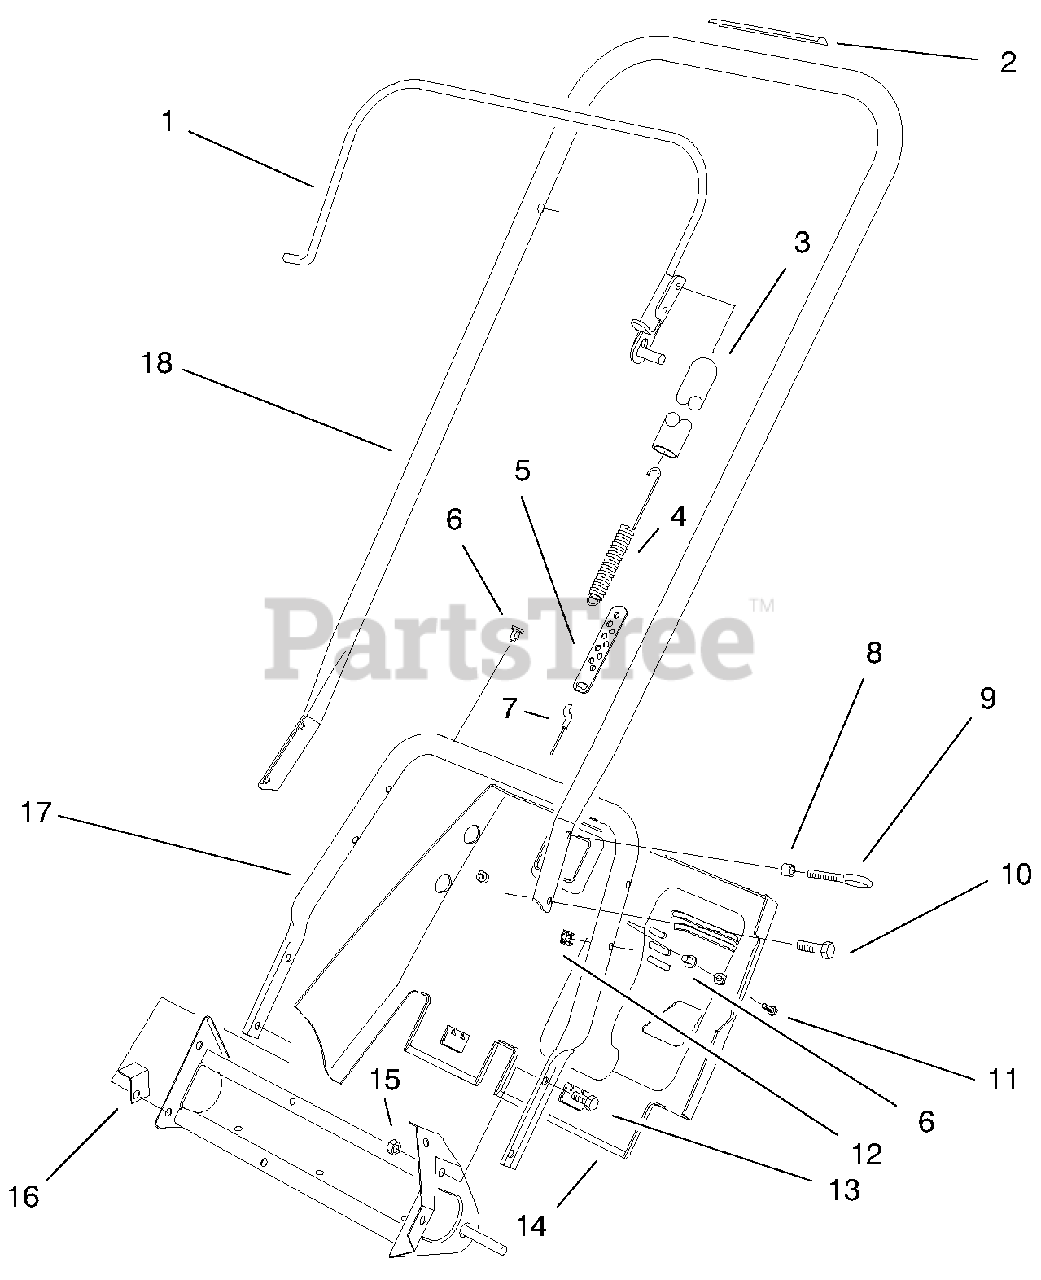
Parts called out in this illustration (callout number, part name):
1	Bail
2	Decal-Rotor Drive
3	Cover-Spring
4	Spring-Clutch
5	Adjuster-Cable
7	Cable-Clutch
8	Spacer-Rotor Blade
9	Eyebolt
10	Screw-Slot Hex Hd.
11	Screw-Thread Form Acorn Head
12	Nut-Speed
13	Screw-Hex Hd.
14	Shroud-Lower
15	Nut-Lock
16	Bracket-Shroud
17	Tube-Handle Lower
18	Handle-Upper
